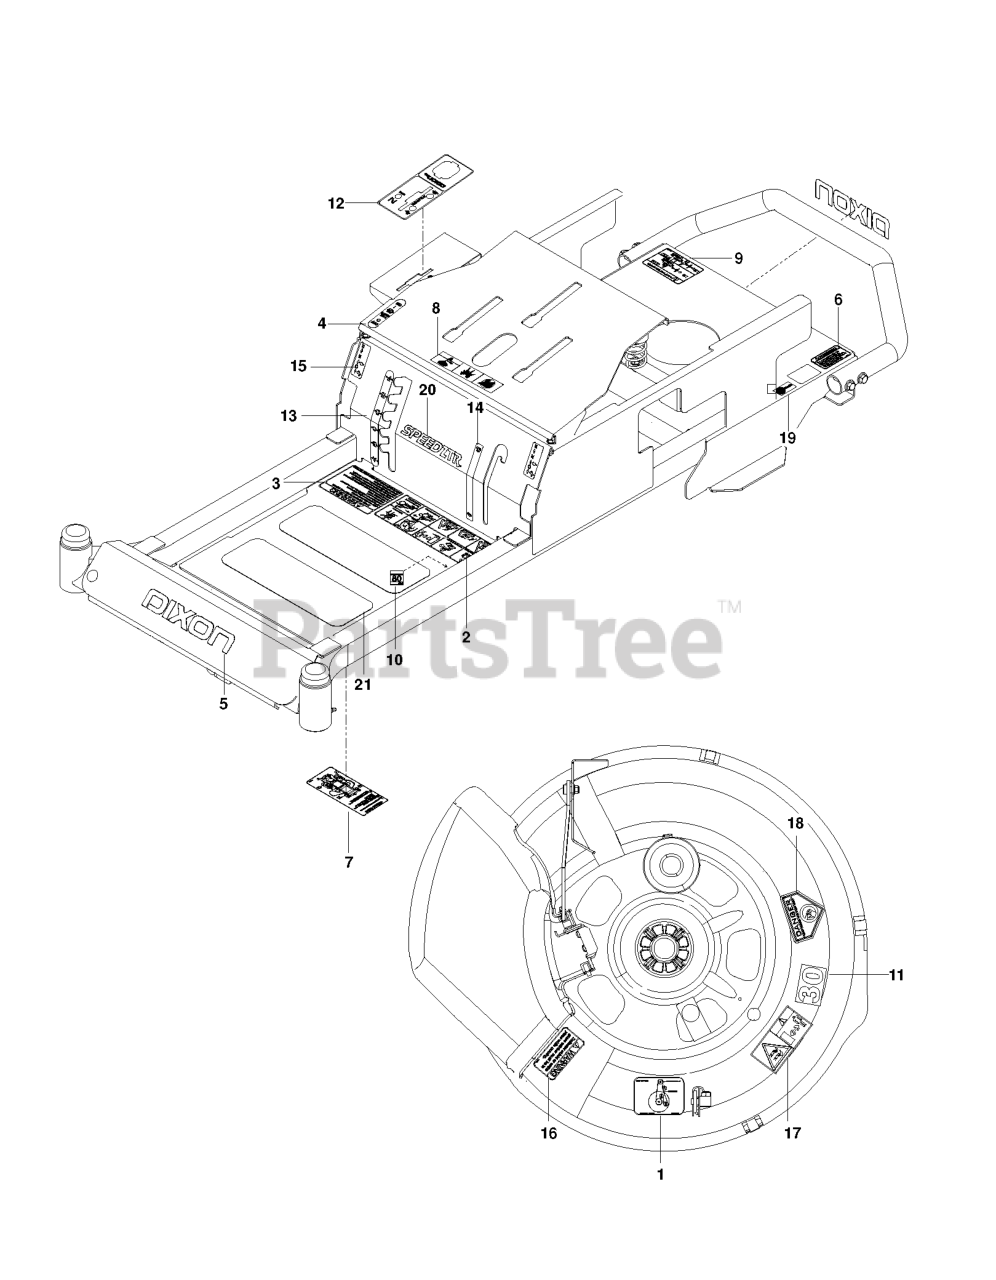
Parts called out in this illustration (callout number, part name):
1	DECAL, BELT ROUTING
2	DECAL, SAFETY WARNING
3	DECAL, WARNING
4	DECAL, PARK BRAKE
6	DECAL, PROP. 65
7	DECAL, SERVICE
9	DECAL, DO NOT MOUNT
11	DECAL, 30, WHITE
12	DECAL, CONTROL PANEL
13	DECAL, DECK HEIGHT
14	DECAL, BLADE ENGAGEMENT
15	DECAL, MOTION CONTROL
16	DECAL, CAUTION
17	DECAL, EURO SEVERING
18	DECAL, CPSC
19	DECAL, ECM, AUSTRALIA
20	DECAL, SPEEDZTR 6.5"
21	ANTI-SKID PAD
